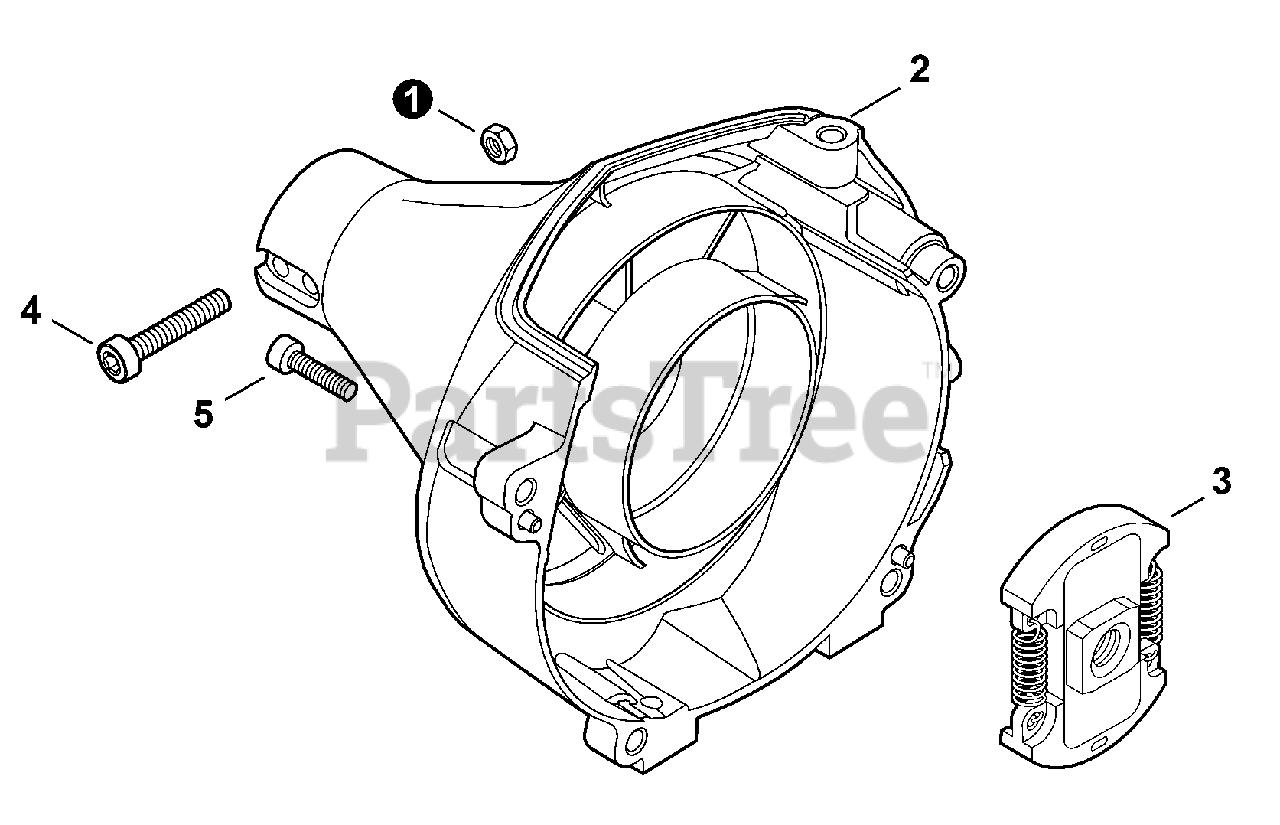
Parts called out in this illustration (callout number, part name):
1	NUT - 5
2	COVER ASSY, FAN
3	CLUTCH ASSY
4	BOLT, TORX 5×25
5	BOLT, TORX 4×16
